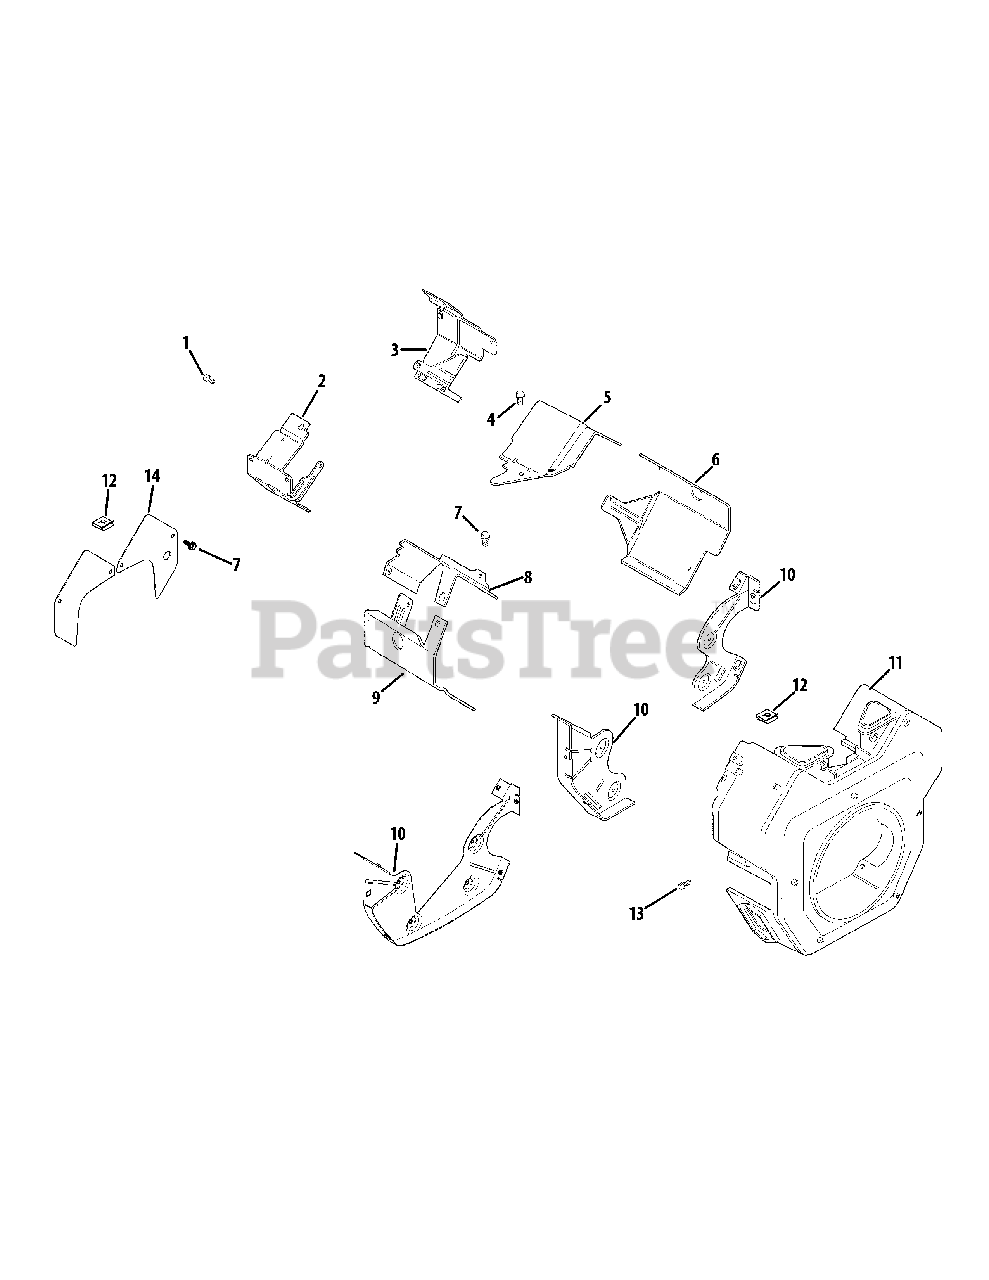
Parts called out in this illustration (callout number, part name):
1	Flange Screw, M6 x 1.0 x 10
2	Ducted Air-Oil Filter Baffle
3	Ducted Air-Starter Baffle
4	Thread Forming Screw
5	Valley Baffle, #1 Cylinder
6	Cylinder Baffle Kit, #1 Side
7	Thread Forming Screw
8	Valley Baffle, #2 Cylinder
9	Cylinder Baffle Kit, #2 Side
10	Backing Plate Kit
11	Blower Housing Assembly Kit
12	Baffle Mounting Clip
13	Thread Forming Screw
14	Access Panel Kit
